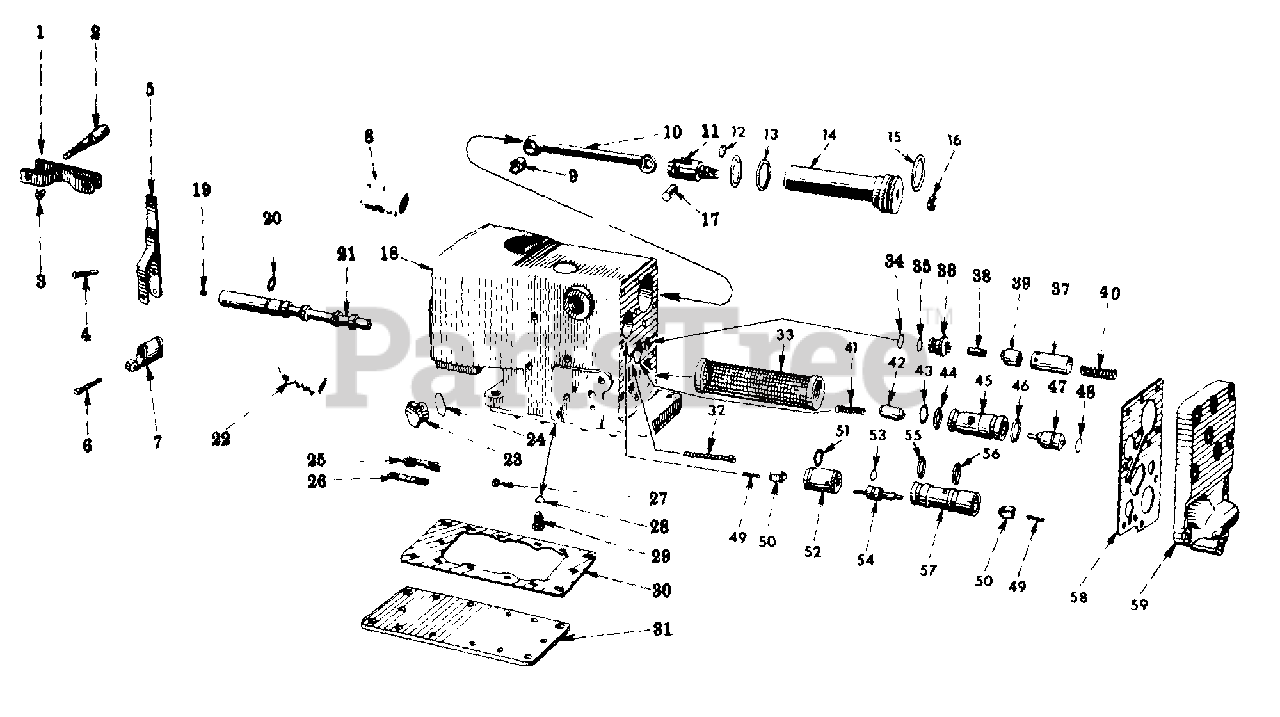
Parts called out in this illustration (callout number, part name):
1	LINK ASSY, CONTROL VALVE OPERATING
2	PIN, CONNECTING ROD
3	PIN, CONTROL VALVE OPERATING LINK
4	PIN, CONTROL VALVE
5	LEVER ASSY, CONTROL VALVE OPERATING
6	PIN, CONTROL VALVE OPERATING LEVER
7	YOKE, CONTROL ROD ADJUSTABLE
8	BOOT, PISTON SLEEVE -RUBBER-
9	BUSHING, CONNECTING ROD
10	ROD W/BUSHING, IH-352007-R1, CONNECTING
11	YOKE, CONNECTING ROD
12	O-RING, 7/16 X 5/8 X 3/32
13	RING, PISTON SLEEVE SEAL
15	RING, PISTON SLEEVE SEAL
16	NUT, 1/2-20 PHC GRIPO LOCK TYPE 8
17	PIN, CONNECTING ROD YOKE
18	BLOCK ASSY, CYLINDER
19	SCREW, 1/4-20 X 3/8 HEX-SOC-HD CUP-PT SET
20	RING, CONTROL VALVE SEAL
21	VALVE, CONTROL
22	BOOT, CONTROL VALVE -RUBBER-
23	PLUG, 7/8-18 HEX-HD OUTSIDE FILLER CAP DRAIN
24	GASKET, FILLER PLUG
25	STOP, CONTROL VALVE OPERATING LEVER
26	LOCK, CONTROL VALVE OPERATING LEVER STOP
27	PLUG, 1/8-27 AUTO. SQ-HD PIPE
28	SCREEN, RELIEF VALVE
29	VALVE ASSY, RELIEF
30	GASKET, CYLINDER BLOCK COVER
31	COVER, CYLINDER BLOCK
32	ORIFICE ASSY -REPLACES IH-351156-R1
33	STRAINER ASSY, CYLINDER BLOCK OIL
34	SPRING, SAFETY VALVE BUSHING TENSION
35	O-RING, 7/16 X 5/8 X 3/32
36	BUSHING, SAFETY VALVE INNER
37	BUSHING, SAFETY VALVE OUTER
38	PISTON, SAFETY VALVE
39	SLEEVE, SAFETY VALVE
40	SPRING, SAFETY VALVE
41	SPRING, PRESSURE REGULATOR CHECK VALVE
42	VALVE, PRESSURE REGULATOR CHECK
43	SPRING, PRESSURE REGULATOR VALVE TENSION
44	O-RING, 3/4 X 1 X 1/8
45	BUSHING, PRESSURE REGULATOR VALVE
46	O-RING, 7/8 X 1-1/8 X 1/8
47	PISTON ASSY, PRESSURE REGULATOR VALVE
48	O-RING, 9/16 X 3/4 X 3/32
49	SPRING, CHECK VALVE
50	VALVE, CHECK
51	O-RING, 11/16 X 7/8 X 3/32
52	BUSHING, CHECK VALVE INNER
53	O-RING, 3/8 X 9/16 X 3/32
54	ACTUATOR, CHECK VALVE
55	O-RING, 3/4 X 1 X 1/8
56	O-RING, 13/16 X 1-1/16 X 1/8
57	BUSHING, CHECK VALVE OUTER
58	GASKET, CYLINDER HEAD
59	HEAD W/PLUGS, IH-444654 AND IH-444660 CYLINDER
